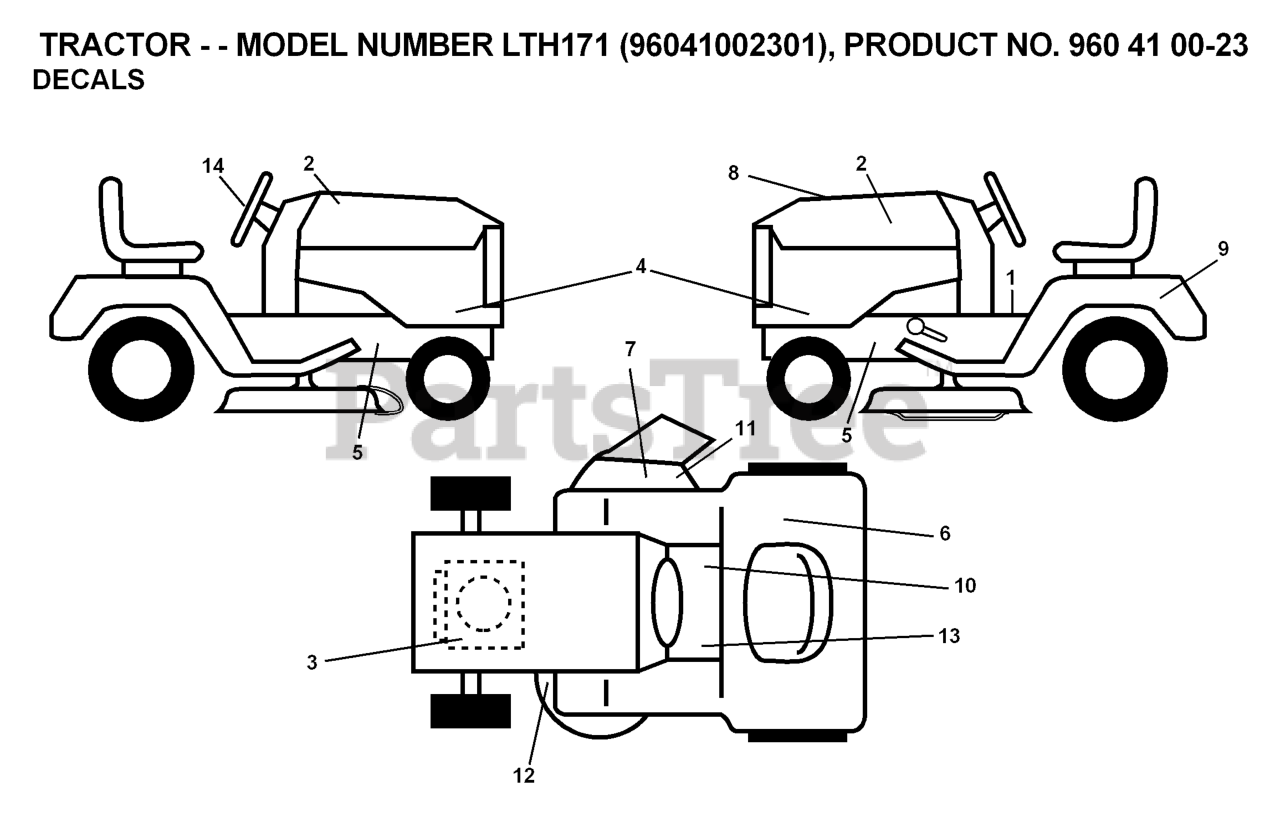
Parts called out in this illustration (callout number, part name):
1	WHEEL, LEFT
2	WHEEL, RIGHT
3	FRONT DECK PLATE, LEFT
4	FRONT PLATE, LEFT
5	FRONT DECK PLATE, RIGHT
6	FRONT PLATE, RIGHT
7	SHOULDER BOLT
9	WASHER, 3/8 SPEC
10	WHEEL PLATE, FRONT
11	AXLE WASHER
13	SLW 3/8 STD
14	NUT 5/16C CENTERLOCK
15	FLAT WASHER 5/16 SAE
16	HCS 3/8-16X1.GRD.5.ZD
17	CARRIAGE BOLT 5/16C X 5/8"
18	TIRE, 9" RIGHT
19	TIRE 9" LEFT
20	BEARING, WHEEL
